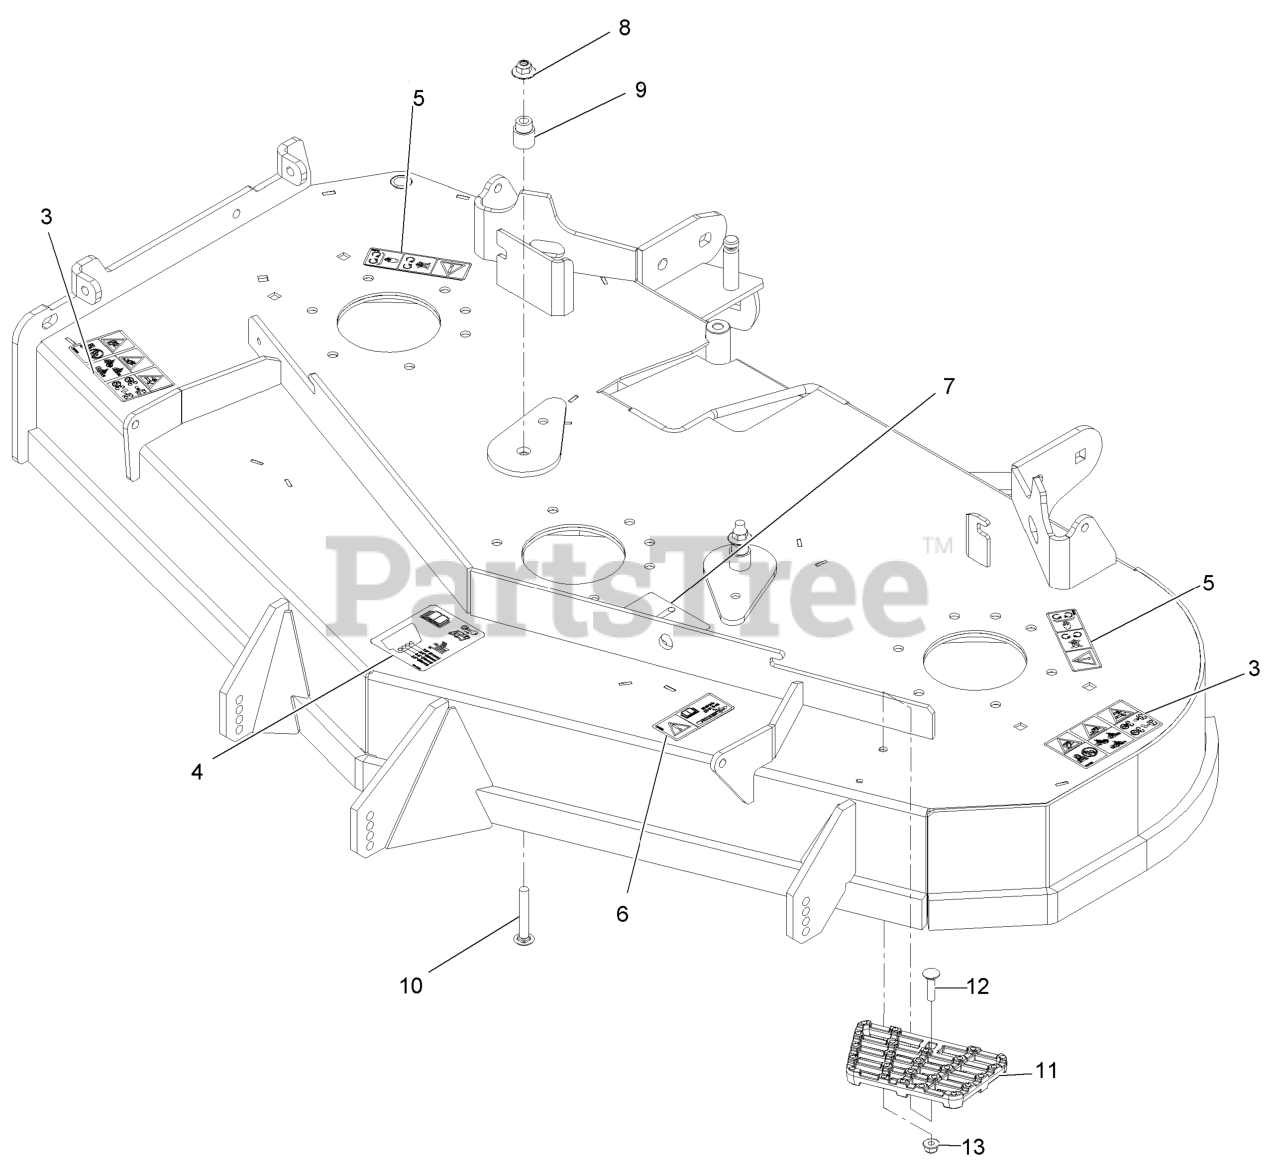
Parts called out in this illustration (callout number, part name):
3	DECAL-DANGER THROWN OBJECTS
4	DECAL-ROLLER, ANTI-SCALP
5	DECAL-COVER, MISSING
6	DECAL-BOLT TORQUE
7	DECAL-BELT ROUTING
8	Nut-Nyloc 3/8-16 Flg
9	BUSHING-IDLER
10	SCREW-CARR
11	STEP-DECK
12	Bolt-Carriage 5/16-18 X 1 1/4
13	NUT-HF, NI
